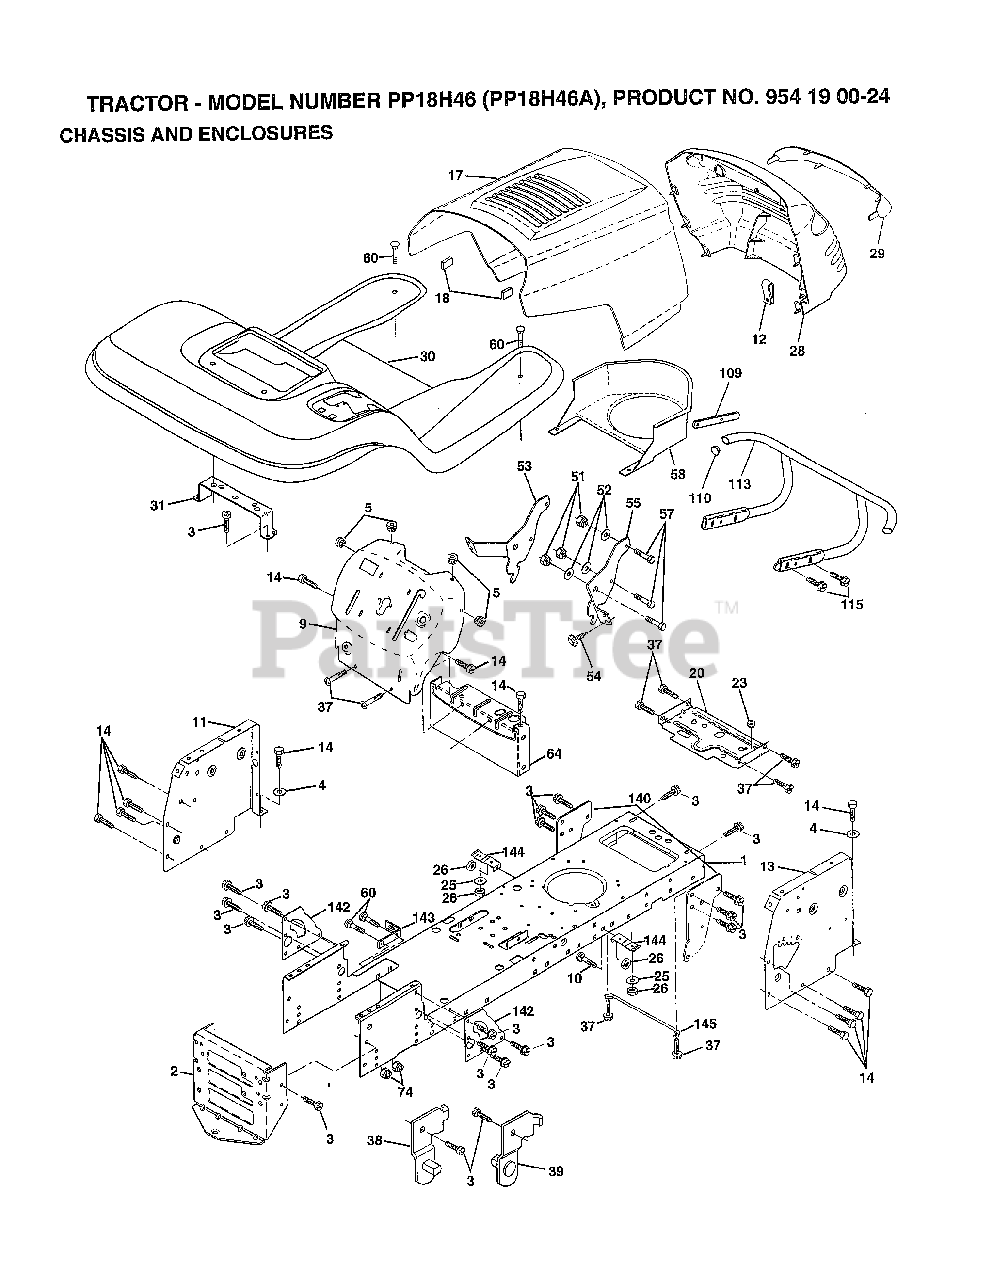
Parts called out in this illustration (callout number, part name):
1	CHASSIS
3	SCREW
4	WASHER
5	BUMPER-HOOD/DASH
11	"PANEL-DASH,LH"
12	CLIP.TINNERMAN
13	"PANEL-DASH,RH"
14	SCREW LT
17	"HOOD W/TRIM,MS428"
20	"PLATE-MTG,BATT/FU"
25	WASHER
26	NUT
28	GRILLE-MS428
29	LENS GRILLE
30	FENDER/FOOTREST
31	BRACKET SUPT FEND
38	BRACKET ASM LH
39	BRACKET ASM RH
51	NUT
52	WASHER
53	BRACKET.GRILLE.LH
54	SCREW.HEX.WS.HD
55	BRACKET.GRILLE.RH
58	AIR.DUCT.ENGINE
60	BOLT
64	DASH-LOWER
109	BRACKET.EXT.BUMP.
110	PLUG.PLASTIC
113	BUMPER.ASM
115	SCREW
140	BRKT SUSPENSION
142	PLATE.REINFORCEMT
143	"BRKT-S'BAR,CHASSI"
145	"ROD POVOT,CHASSIS"
